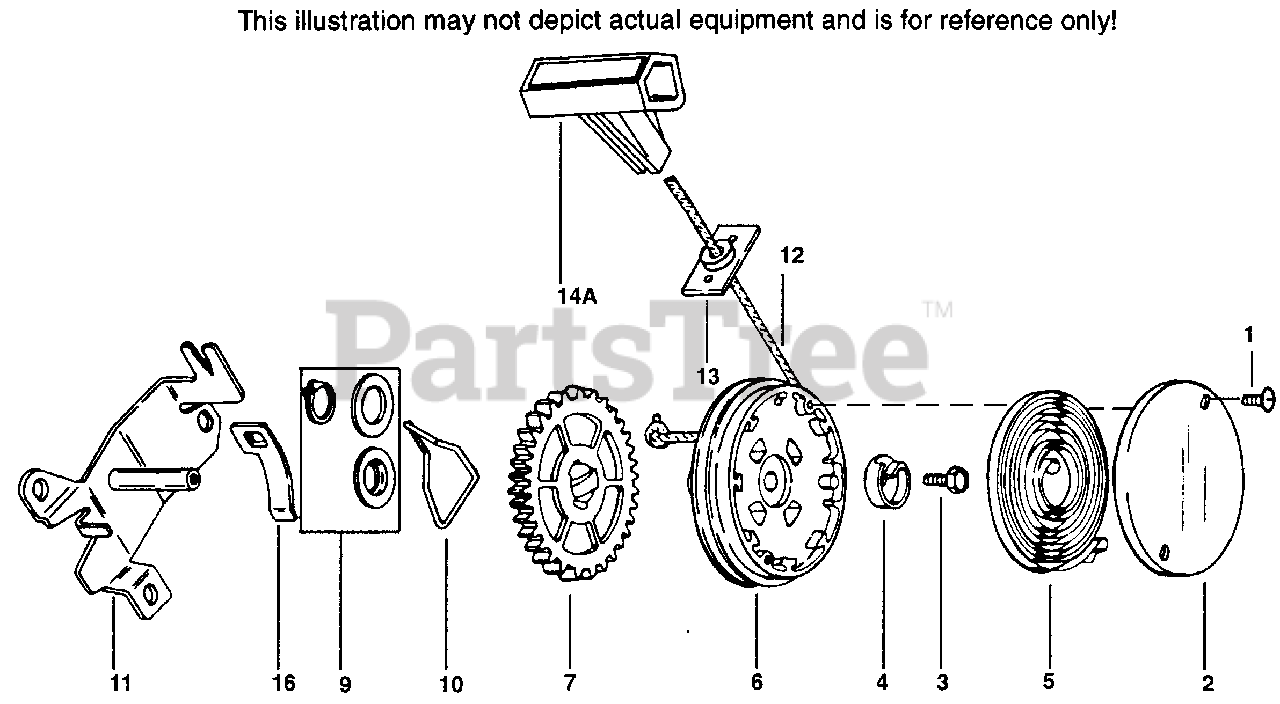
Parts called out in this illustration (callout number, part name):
1	Screw, Cover
2	Cover, Spring
3	Screw, 10-32 x 5/8"
4	Hub, Spring
5	Spring, Rewind
6	Pulley Assy. (Incl. 9)
9	Kit, Thrust washer and snap ring
11	Bracket Assy., Mounting (4 Cycle)
11A	Bracket Assy., Mounting (2 Cycle)
12	Rope & Retainer Assy., Starter Length 61" & 5/32" Dia.
13	Bracket Assy. Can be removed if notre q.
14	Handle Assy., Starter (Incl. 15) also available in 740033B Starter Rope & Handle Kit
15	Insert, Handle
16	Clip, Rope
17	Retainer, Rope
